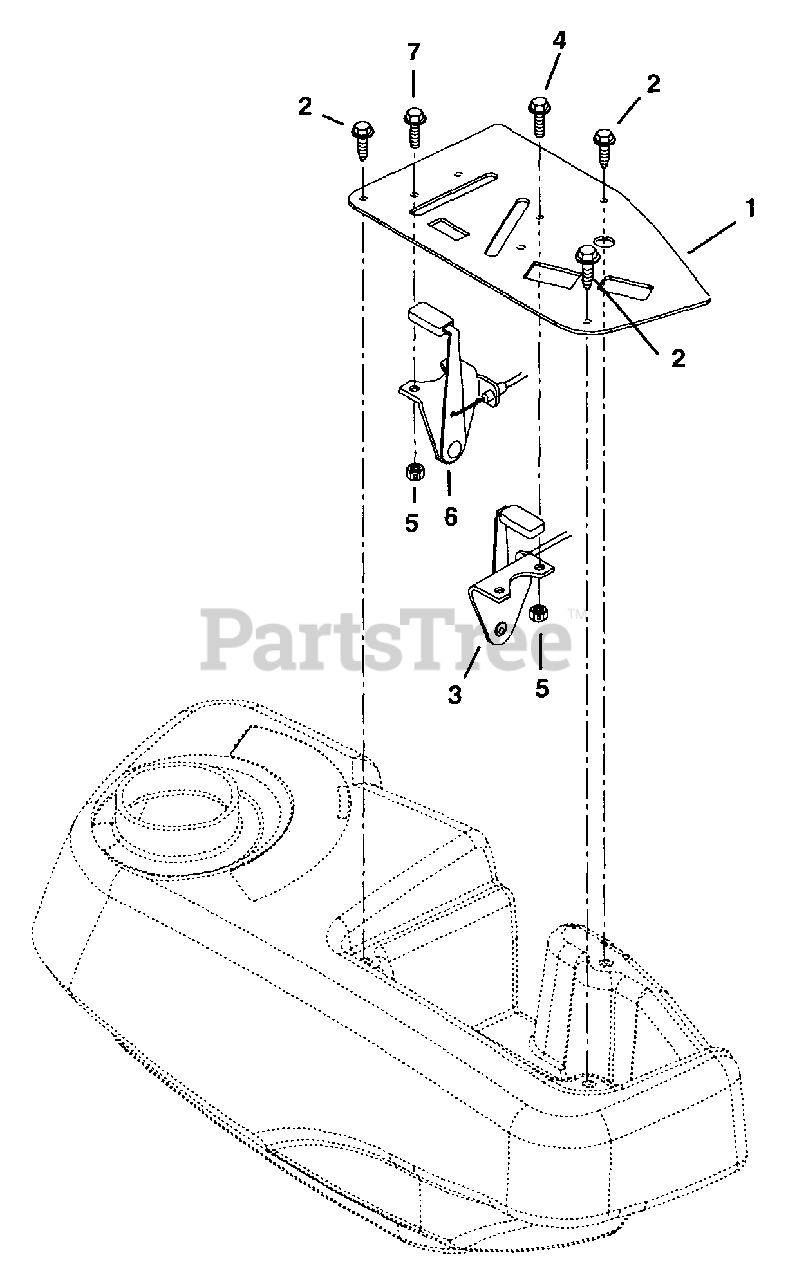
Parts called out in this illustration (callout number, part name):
1	Panel-Control
2	Screw-Machine 10-24 x .50 Hex Washer Head
3	Throttle Control
4	Screw-Machine 10-24 x .50 Hex Washer Head
5	Nut-Locking-Nylon 10-24 With Insert
6	Choke Control
6	Choke-Control
7	Screw-Machine 10-24 x .50 Hex Washer Head
